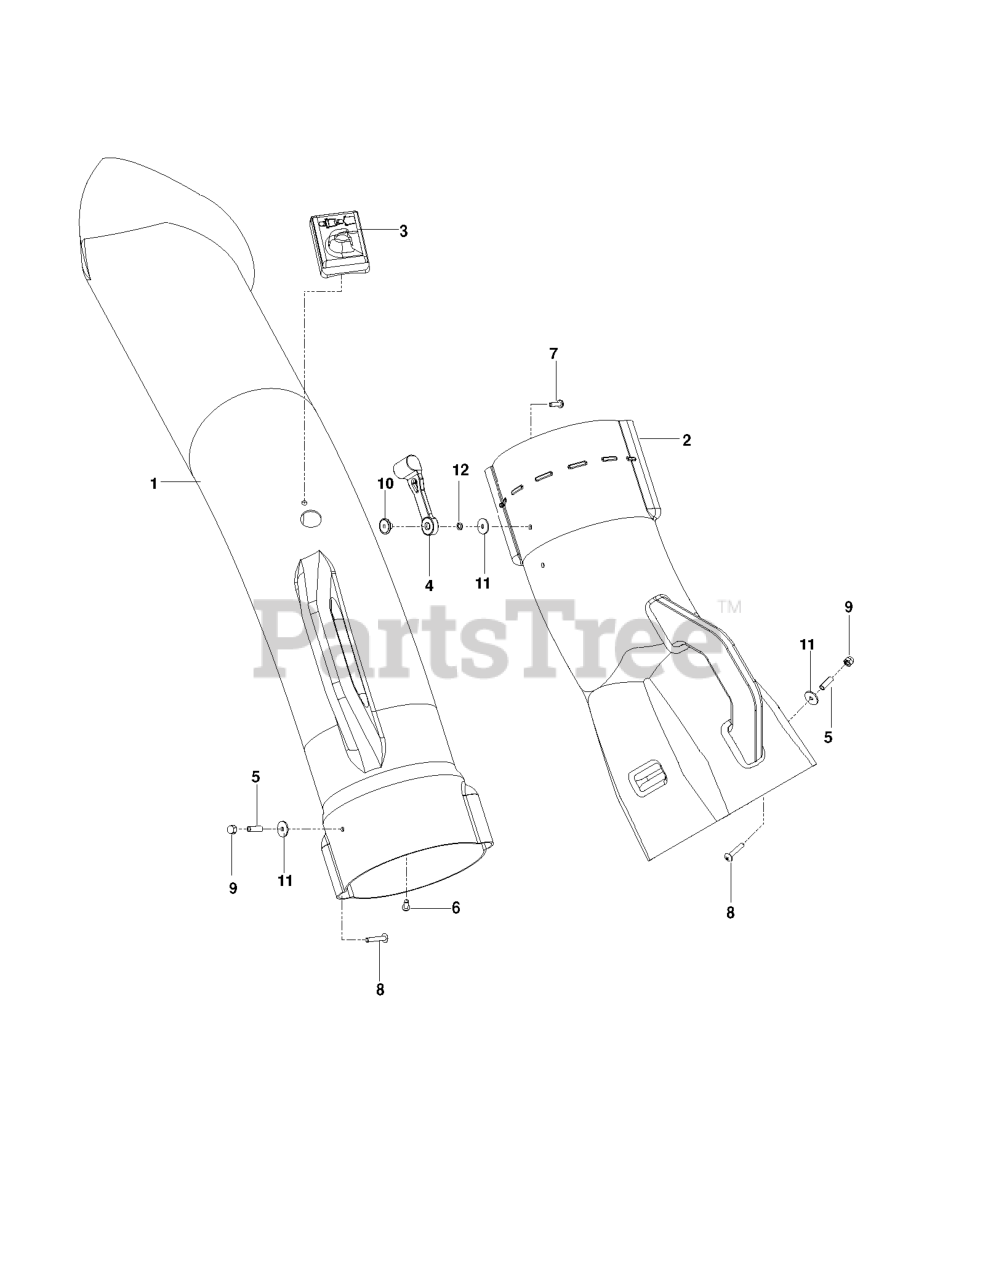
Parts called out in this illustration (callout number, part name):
1	CHUTE, UPPER - TRIMMED
2	CHUTE, MIDDLE
3	DUMP BAG INDICATOR
4	HOOD LATCH
5	BSHG .202X.75 LG SPLIT ZD SPEC
6	SCREW
7	SCREW #10-24 X 5/8
8	SCREW #10-24 X 1-1/8 ZD SPEC
9	NUT 10-24 ACORN ZD
10	NUT 10-24 WELD PLATED
12	WASHER - 3/16 LOCK ZD
